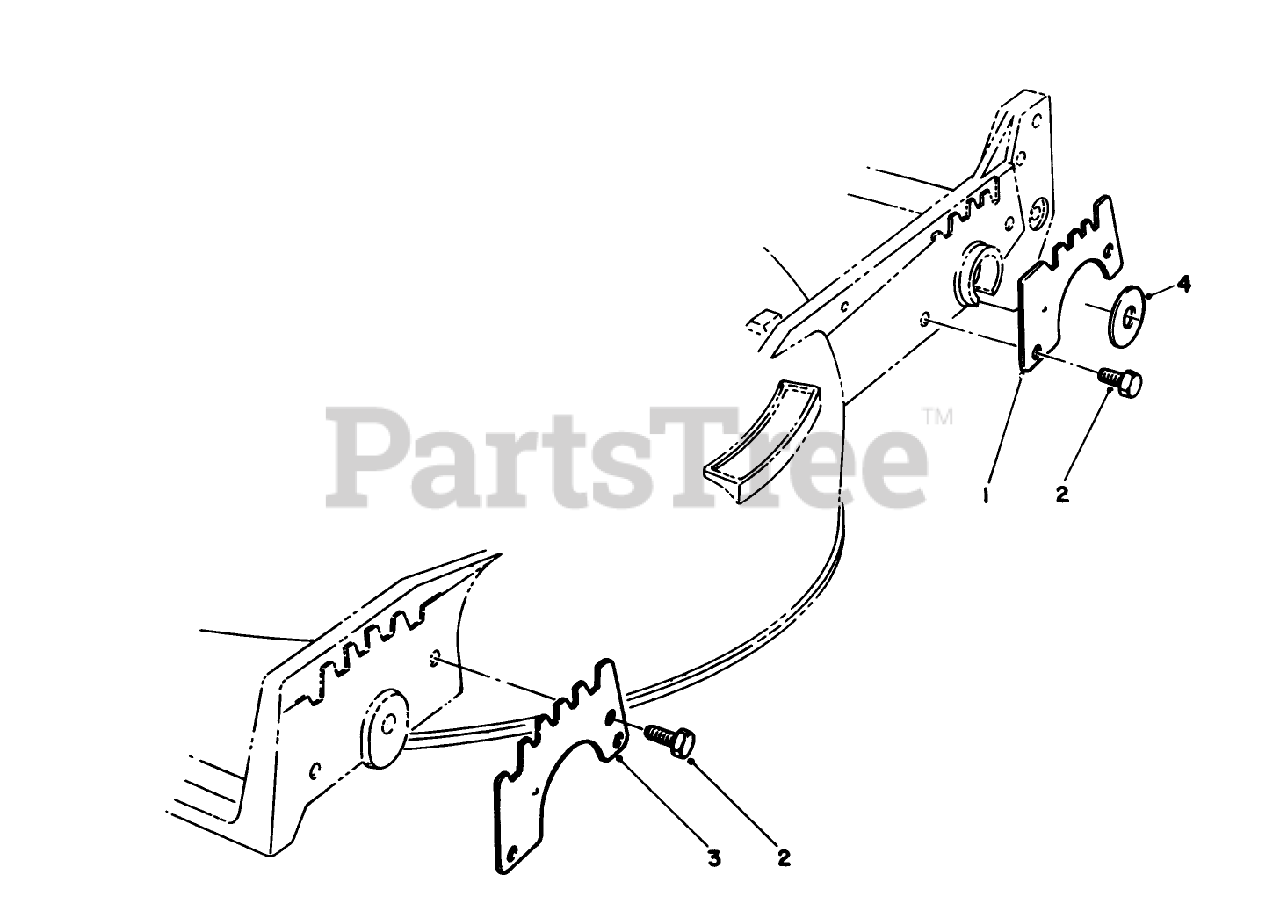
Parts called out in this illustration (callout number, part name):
1	WEAR PLATE,REAR
2	SCREW-HWH
3	WEAR PLATE
4	PIVOT WASHER
